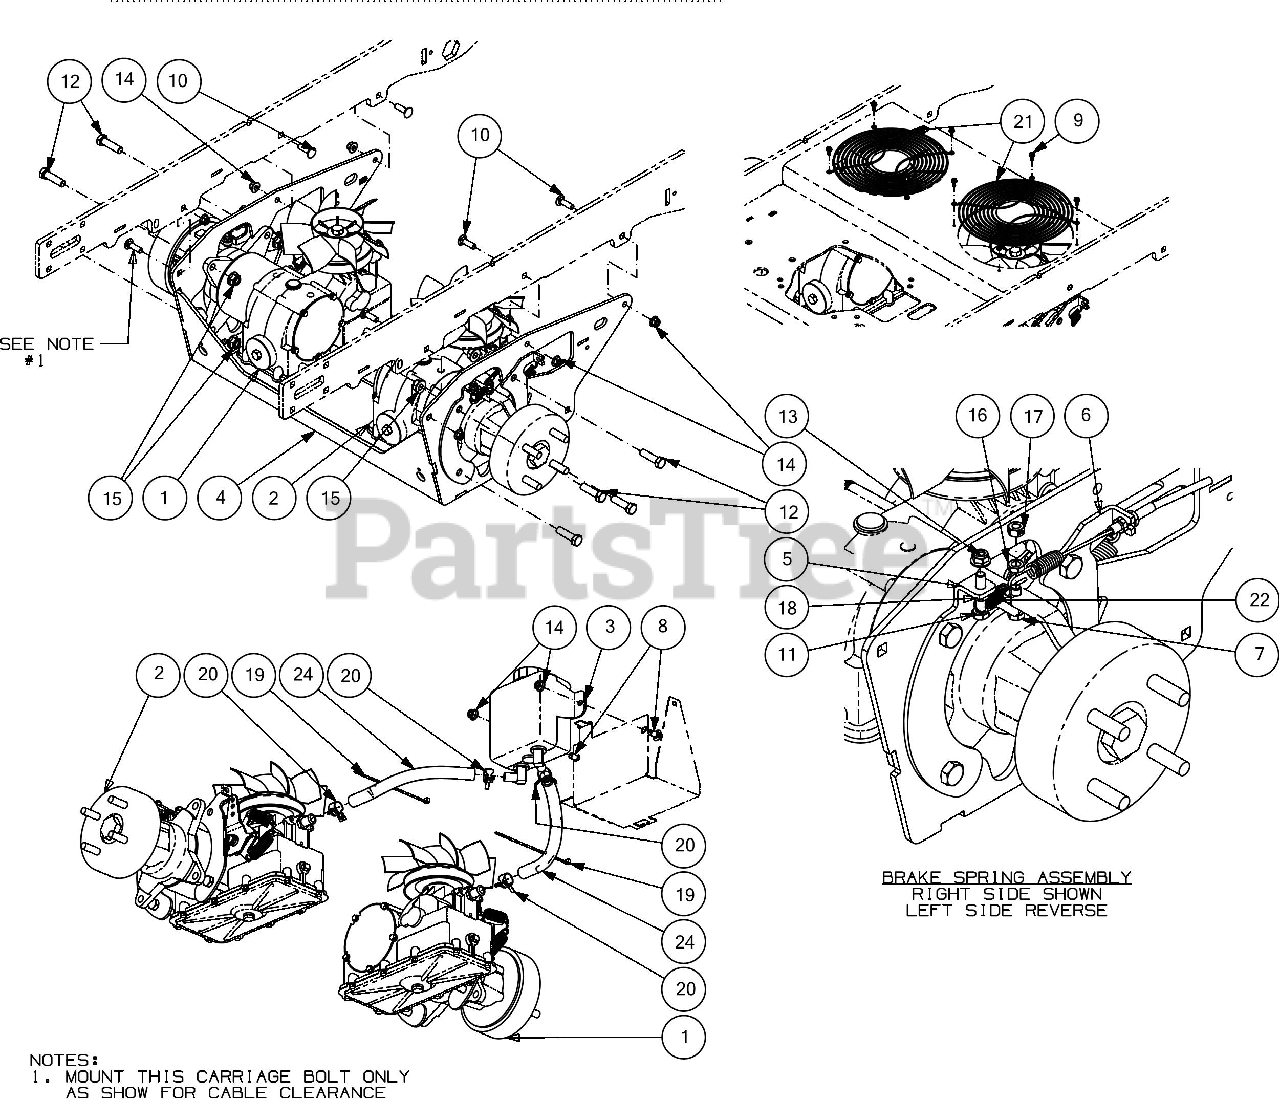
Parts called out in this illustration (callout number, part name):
1	TRANSMISSION ASSEMBLY (LH)
2	TRANSMISSION ASSEMBLY (RH)
3	TANK ASSEMBLY (1.5 QT)
4	TRANSMISSION BRACKET ASSEMBLY
5	BRAKE SPRING BRACKET
6	BRAKE CABLEB RACKET
7	SCREW 5/16-18 X 1.0 GR5
8	CARRIAGE BOLT 3/8-16 X .750 GR5
9	SCREW 10-24 X 0.500
10	CARRIAGE BOLT 3/8-16 X1.25 GR5
11	SCREW 5/16-18 X 1.5 LG
12	BOLT 1/2-13X1.75 GR5
13	FLANGE LOCK NUT 5/16-18
17	HEX NUT
18	HEX NUT
19	CABLE TIE 7"
20	HOSE CLAMP
22	EXTENSION SPRING .500 OD X 1.71
24	HOSE-OIL 5/8 X 12
